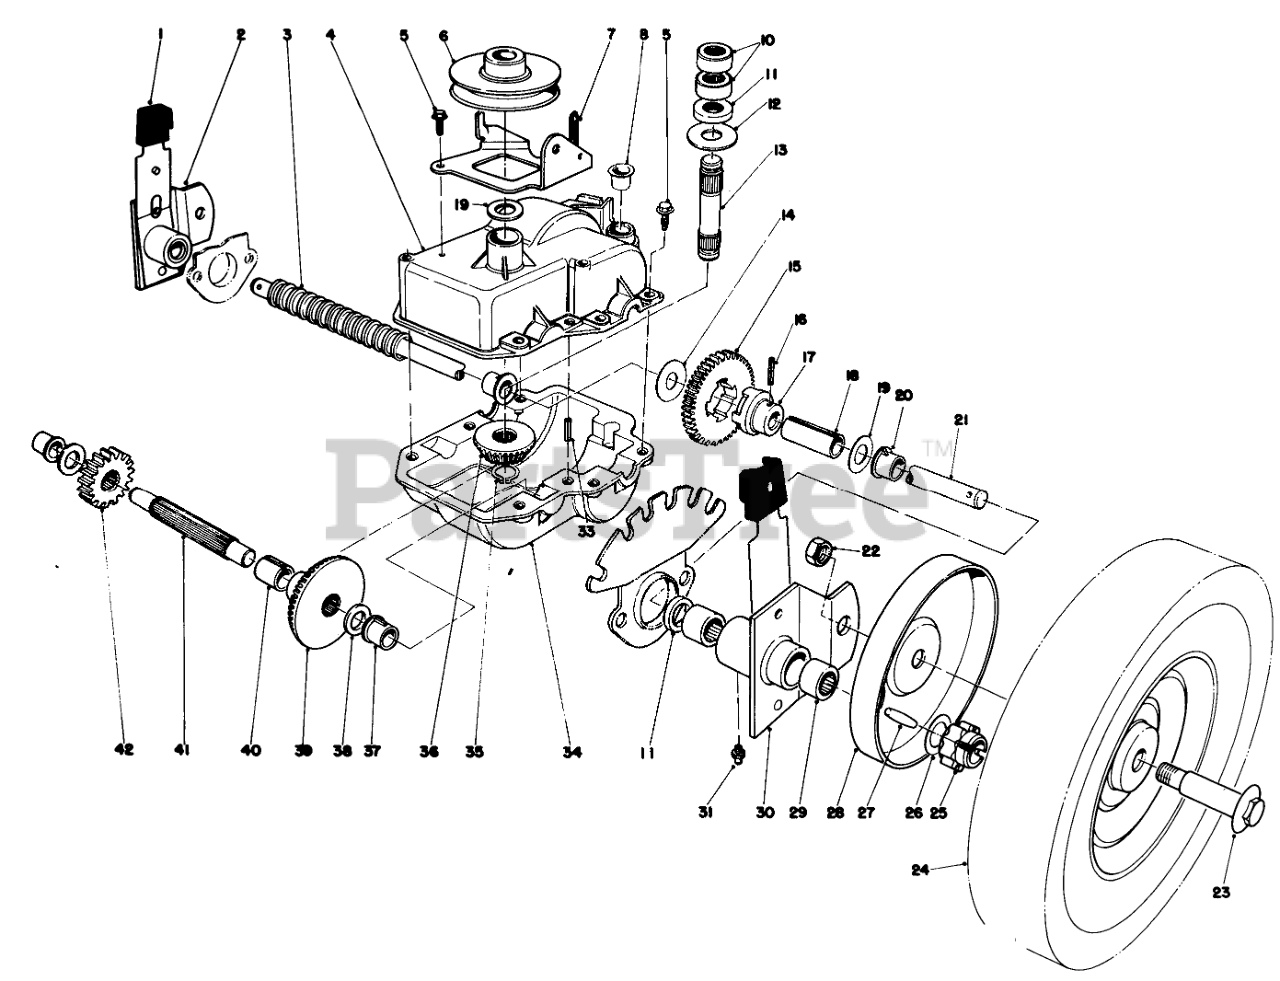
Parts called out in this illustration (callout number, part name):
1	KNOB-ARM
2	Pivot Arm L.H. (Incl. Ref. #29 & 32)
3	Cover-Drive Shaft
4	Case Upper
5	Screw
6	Pulley
7	Belt Guide Bracket
8	Caplug
10	Bearing
11	Seal
12	Thrust Washer
13	Input Shaft & Pulley Ass-y (Incl. Ref. #6)
14	WASHER
15	Gear
16	COIL PIN
17	ADAPTER DRIVE
18	Spacer-Output Shaft
19	WASHER-PLAIN
20	Bushing
21	DRIVE SHAFT
22	Nut
24	Wheel & Tire
25	Pinion
26	WASHER-THRUST
27	PIN-GROOVED
28	WHEEL COVER
29	Needle Baring
30	Pivot Arm R.H. (Incl. Ref. #29 & 32)
31	FITTING-GREASE
33	ROLL PIN 3/16 X 1 IN
34	LOWER GEAR CASE CAST
35	RING-RETAINING
36	Pinion Bevel
37	Botching Shaft
38	WASHER-THRUST
39	Bevel Gear
40	Spacer-Short Shaft
41	Short Shaft
